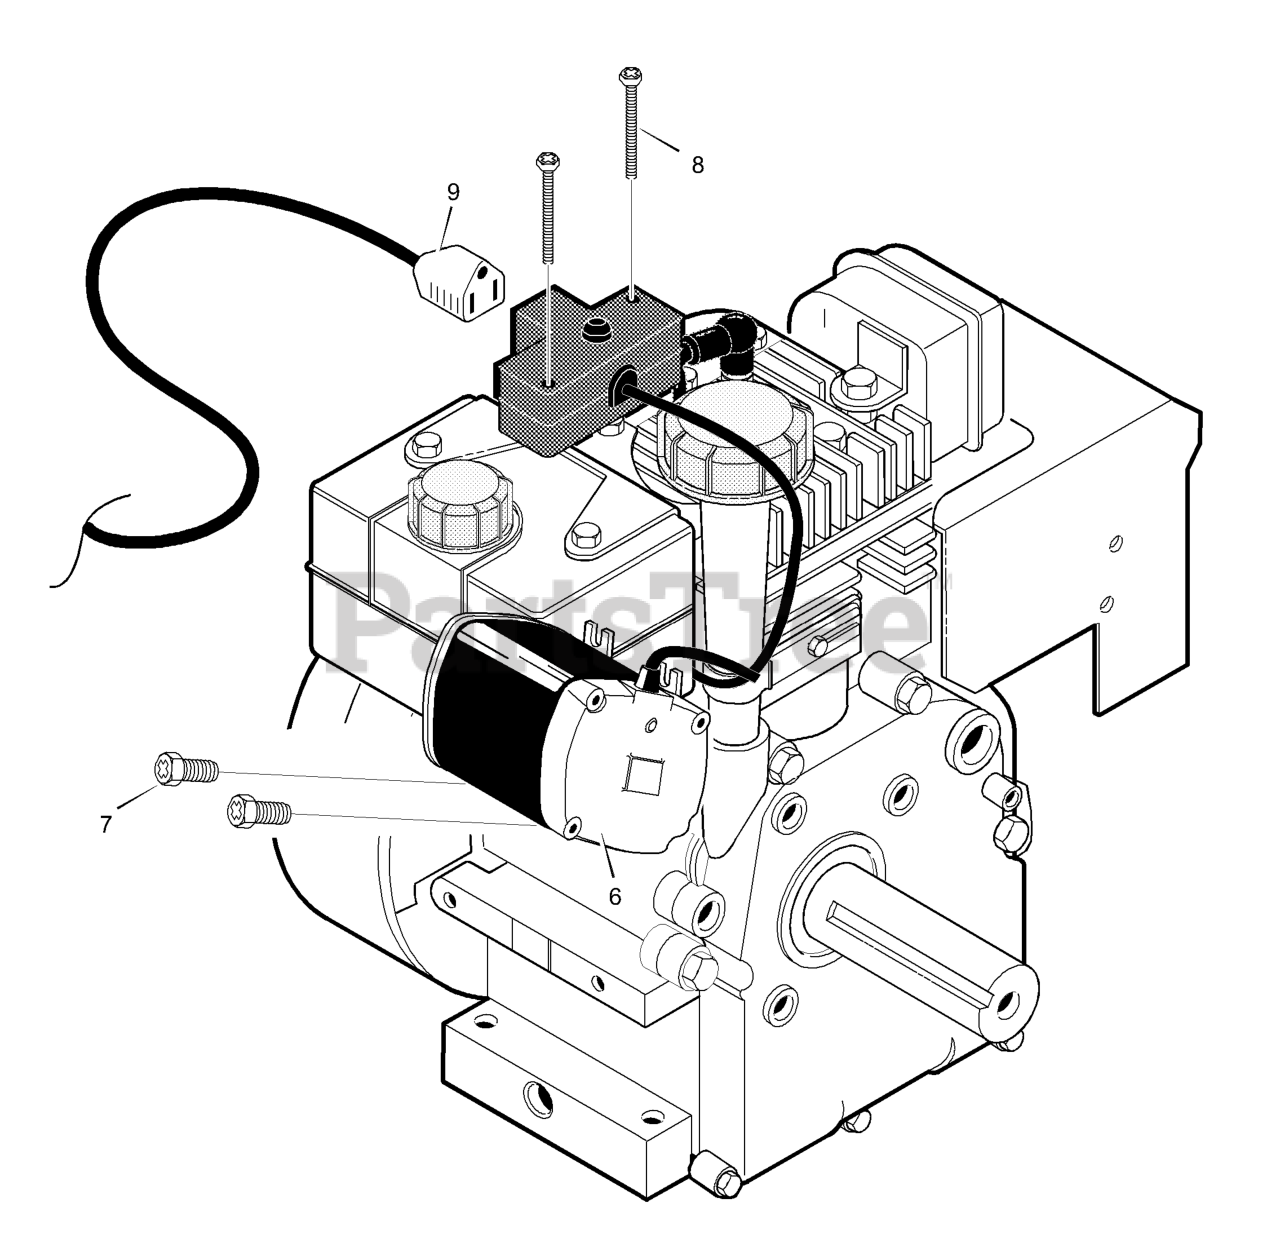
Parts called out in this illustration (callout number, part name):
6	MOTOR, STARTER
8	SCREW
9	CORD, Electric, 10FT. 110V
